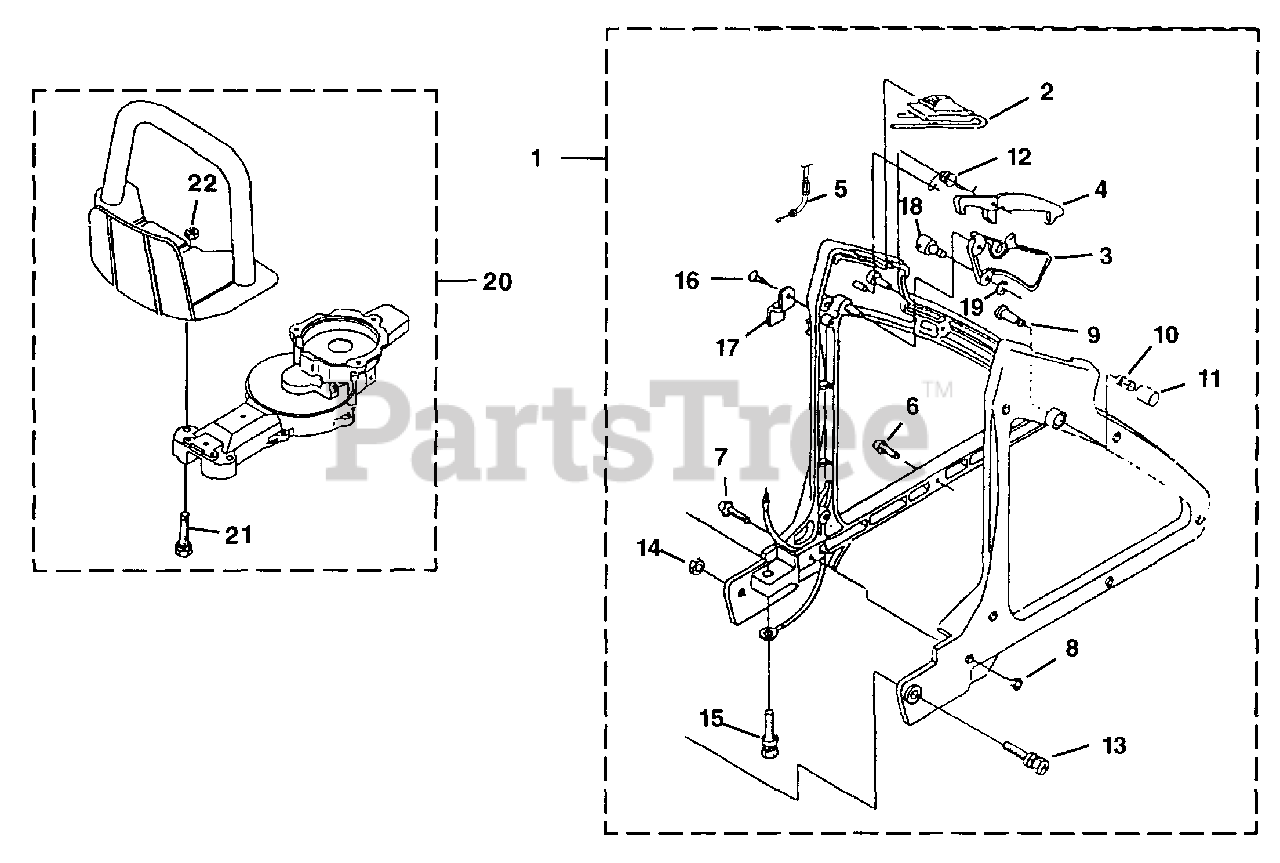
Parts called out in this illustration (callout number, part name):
1	REAR HANDLE COMPLETE
2	SWITCH ASSEMBLY
3	TRIGGER-Throttle
4	LATCH-Throttle
5	CASLE - Throttle
6	SCREW (M4 x 16 W SW)
7	SCREW (M4 x 30 W SW)
8	NUT (M4)
9	LOCK-Throttle Start
10	SPRING-Throttle Lock
11	BUTTON-Throttle Lock
13	SCREW (M6 x 50 W SW & PW)
14	NUT (M6)
15	SCREW (M6 x 40 W SW & PW)
16	SCREW (M4 x 10)
17	HOLDER-Cable
18	CABLE-Swivel
19	SNAP RING
20	FRONT HANDLE ASSEMBLY
21	SCREW (M6 x 35 W SW & PW)
22	NUT (M6)
